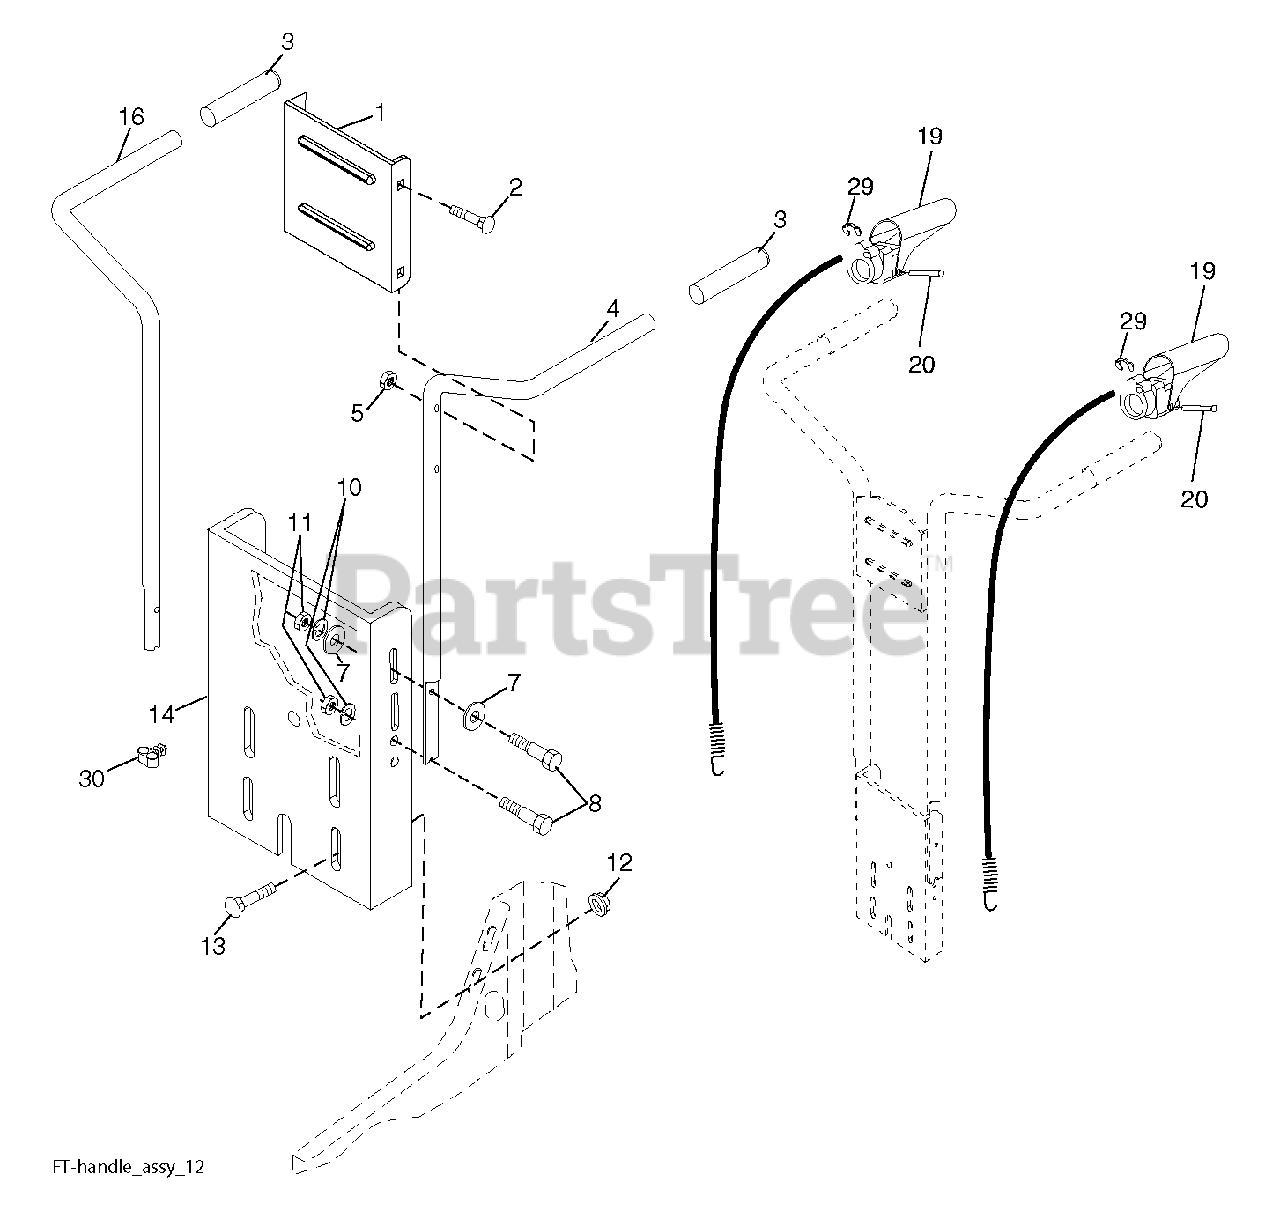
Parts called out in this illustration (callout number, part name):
3	GRIP.HANDLE.BLACK
4	HANDLE.LH.D.BEND.BLACK
5	NUT, LOCK 5/16-18
7	WASHER
8	BOLT
10	LOCKWASHER
12	NUT
13	BOLT, RDHD SQNK 5/16-18 X 3/4
14	PANEL.HANDLE.RED.667.PNT
16	HANDLE.RH.D.BEND.BLACK
20	PIN, PIVOT
29	RETAINING RING
30	CLIP.ROUTING DUAL
